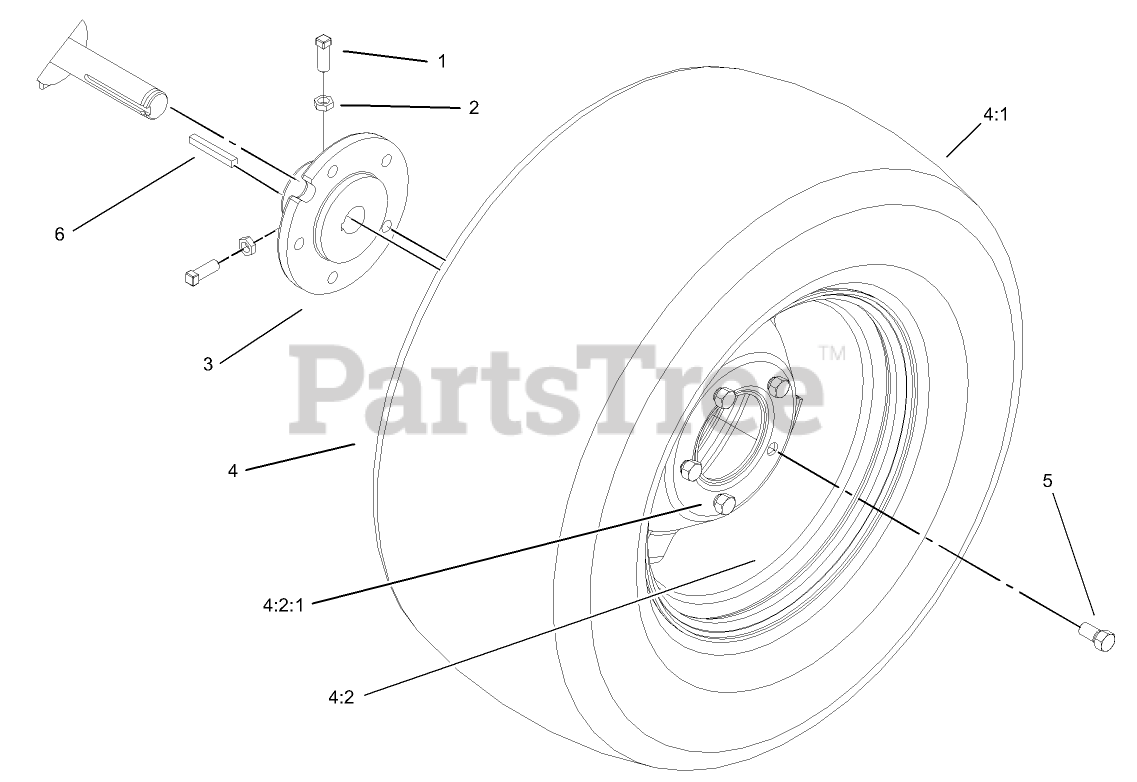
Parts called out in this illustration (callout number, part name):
1	SCREW-SET, SQH
2	NUT-JAM
3	HUB-WHEEL
4	Loose Parts Package
4:2	WHEEL
4:2:1	VALVE
5	BOLT-LUG
6	KEY-SQUARE
